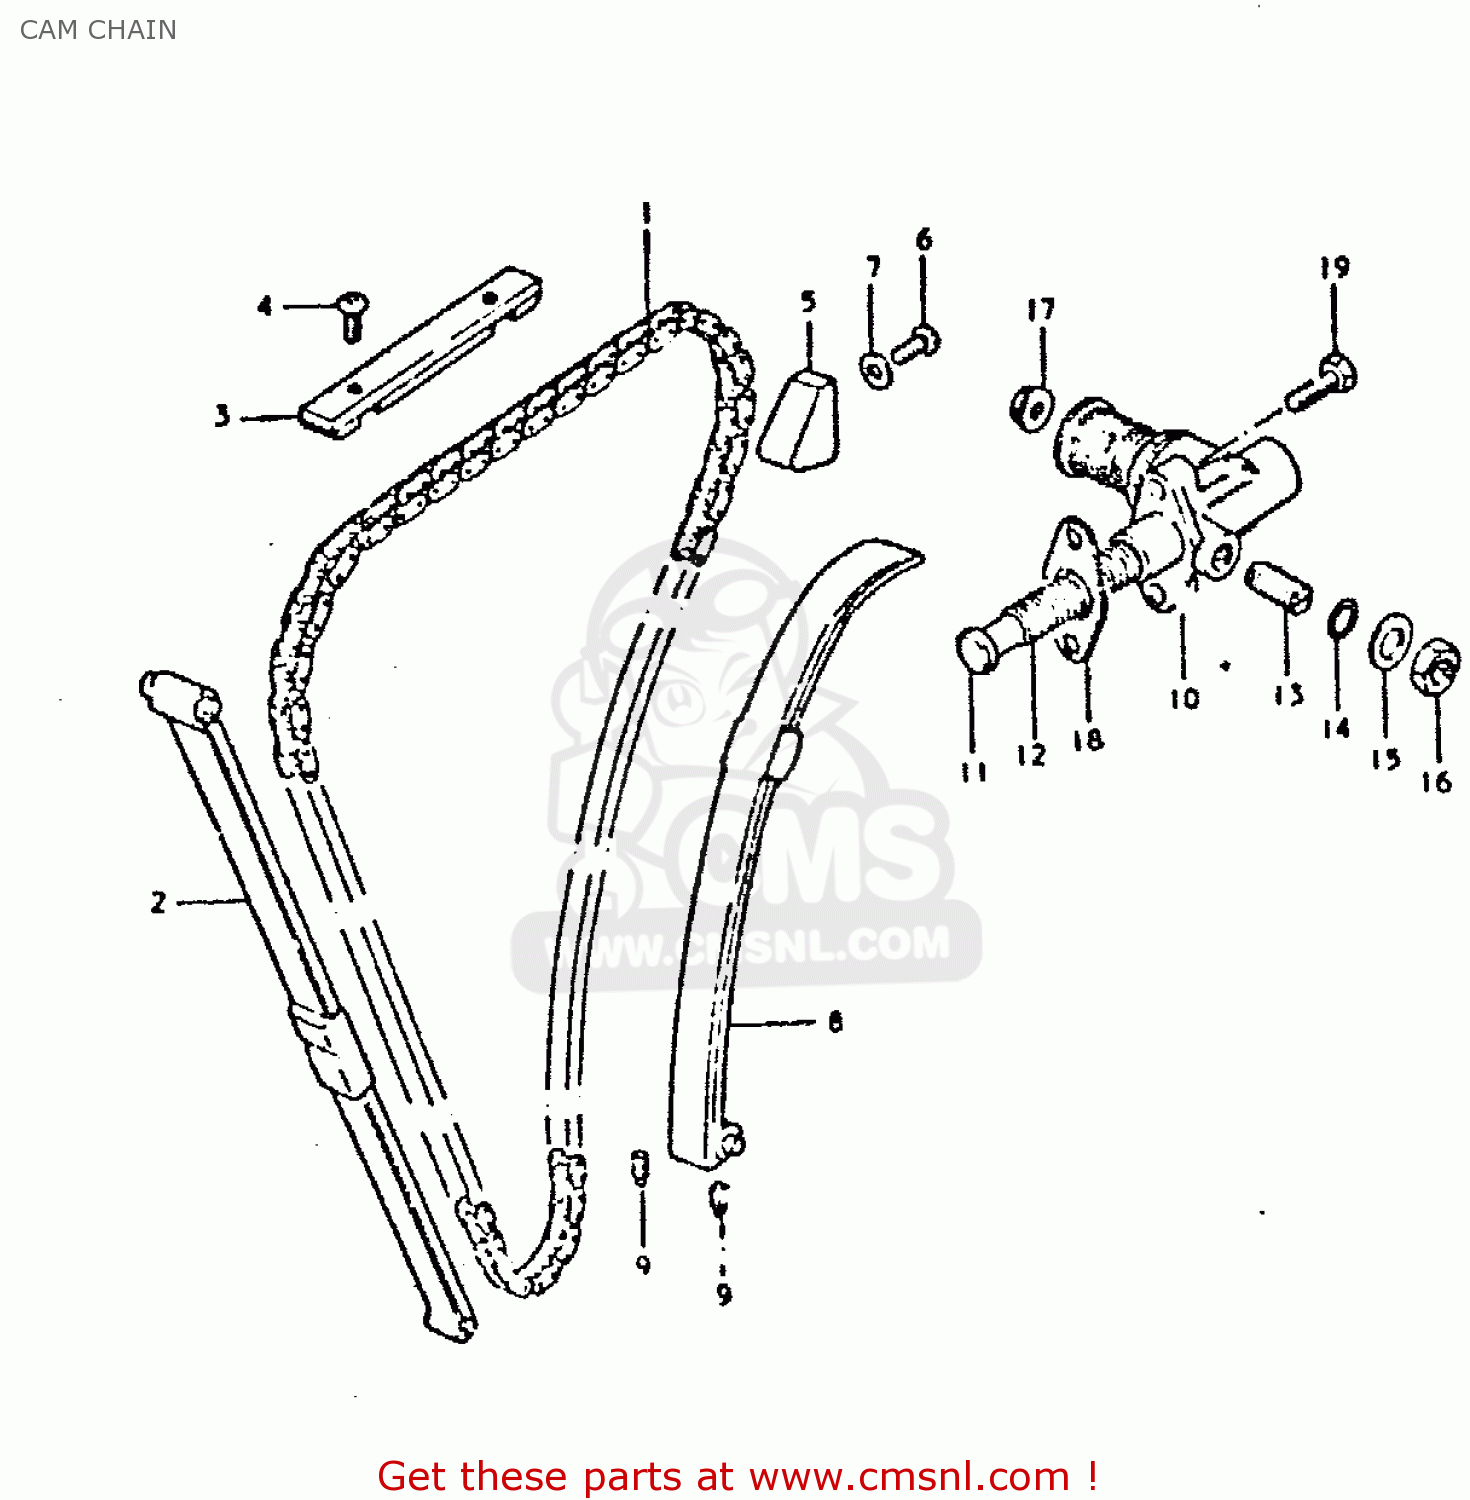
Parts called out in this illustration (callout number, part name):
1	CHAIN,CAMSHAFT DRIVE(120L)
2	GUIDE, CAM CHAIN NO.1
3	GUIDE,CAM CHAIN NO.3
4	SCREW
5	GUIDE,CAM CHAIN
6	SCREW 6X12
7	GASKET (NAS)
8	TENSIONER,CAM CHAIN
9	CUSHION,CAM CHAIN TENSIONER
10	ADJUSTER ASSEMBLY,TENSIONER
11	ROD,PUSH
12	SPRING
13	SCREW
14	O-RING
15	WASHER
16	NUT
17	NUT
18	GASKET,TENSIONER ADJUSTER (MCA)
19	SCREW (6X25)
